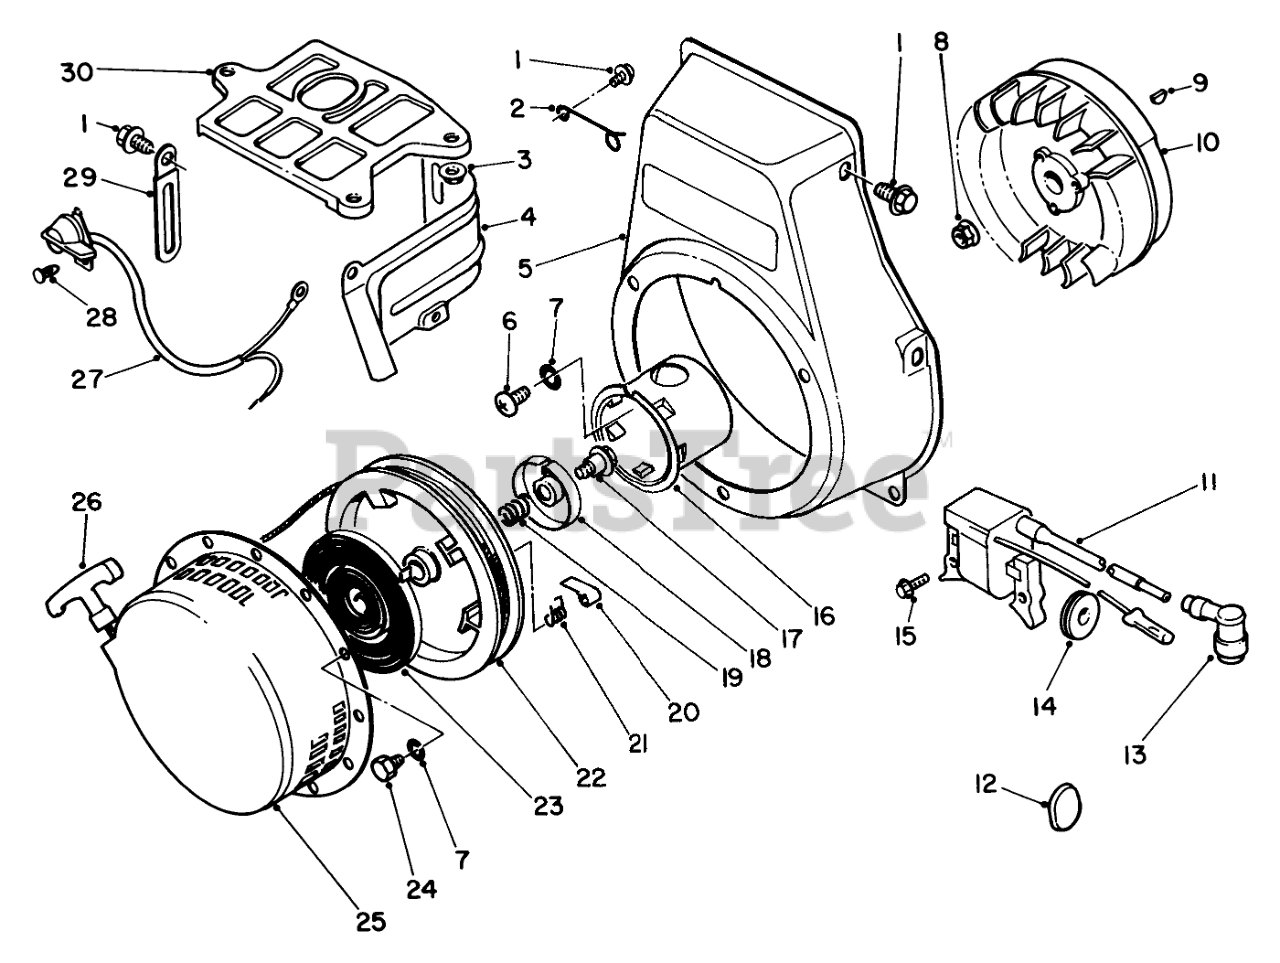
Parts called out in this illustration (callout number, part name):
2	CLAMP
4	Cowling-Side
5	Cover-Cooling Fan
6	Screw
7	LOCKWASHER
10	Flywheel
11	Coil-Primary
13	SPARK PLUG CAP
14	Grommet
16	Pulley-Starter
18	Retainer
19	SPRING
21	SPRING
22	Reel
23	SPRING
25	Recoil Starter Assembly(Incl. Ref. #7, 17-24 & 26)
26	Grip-Hand
27	SWITCH
29	CLAMP
30	Cowling-Upper
